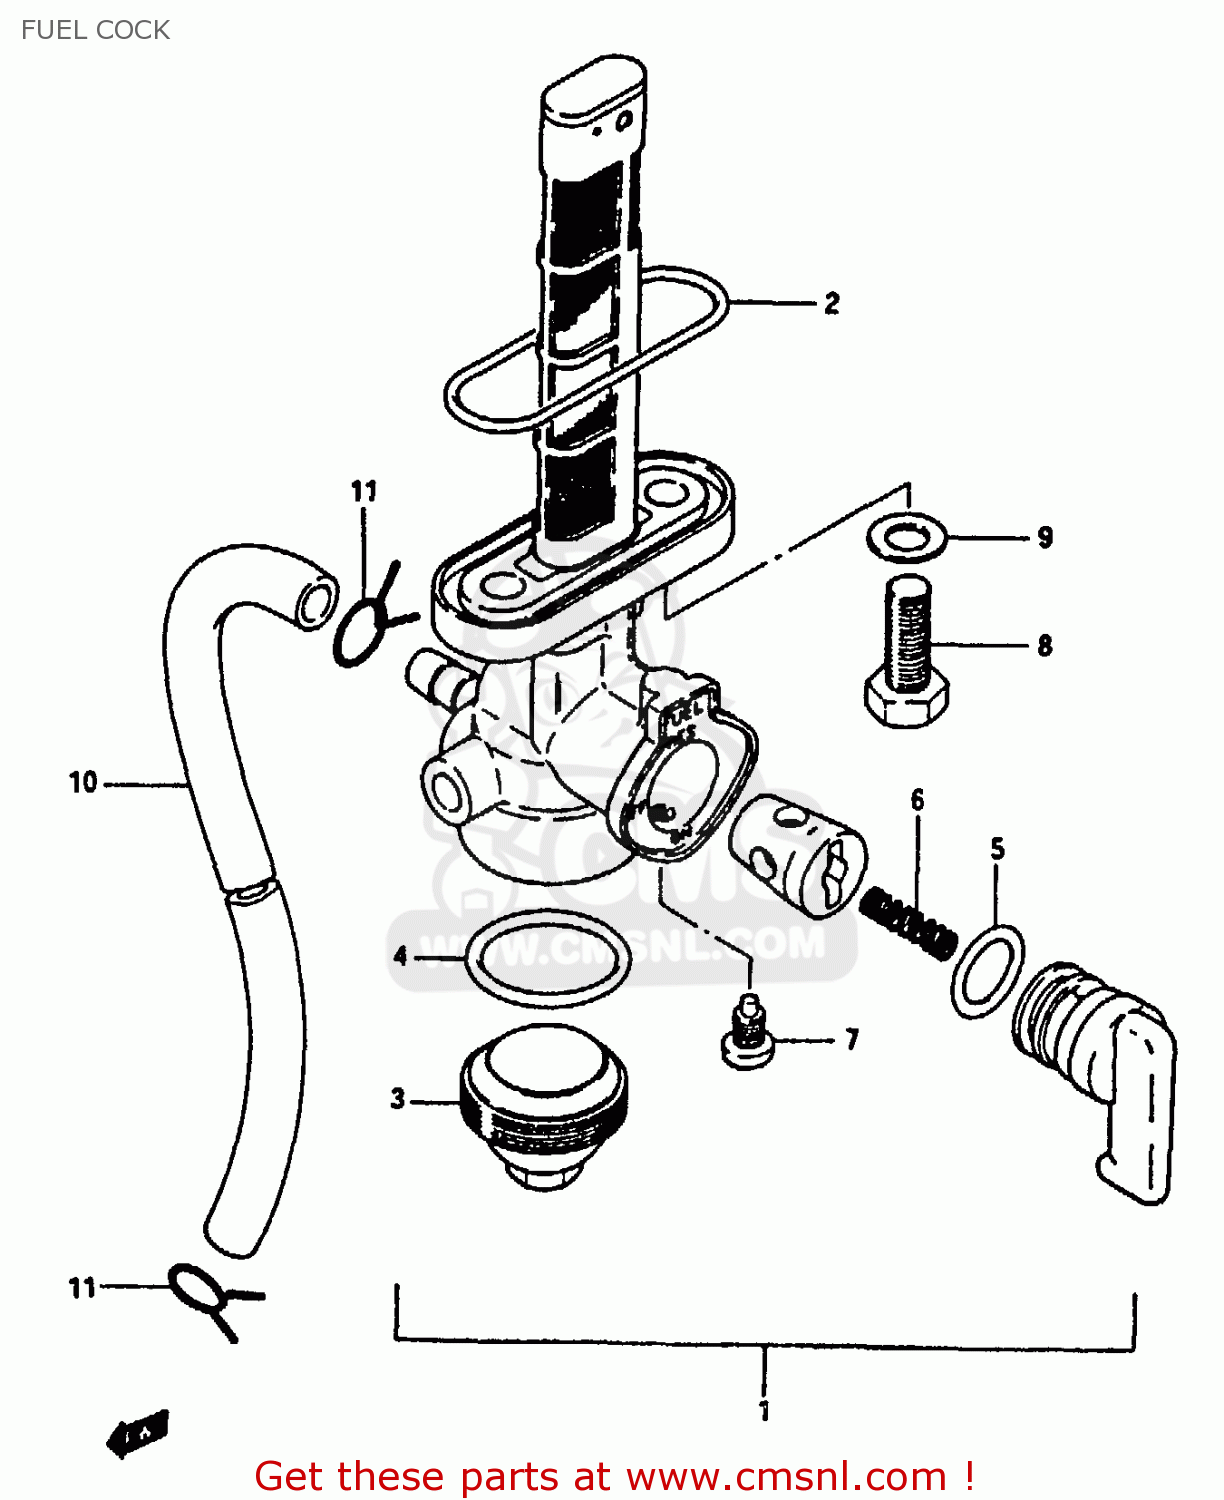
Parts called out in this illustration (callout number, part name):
1	COCK ASSEMBLY,FUEL
2	O RING,FUEL COCK
3	CUP,STRAINER
4	GASKET,FILTER (NAS)
5	O-RING
6	SPRING
7	SCREW
8	BOLT(6X20)
9	GASKET(6.4X11.5X0.8) (NAS)
10	HOSE
11	CLIP
